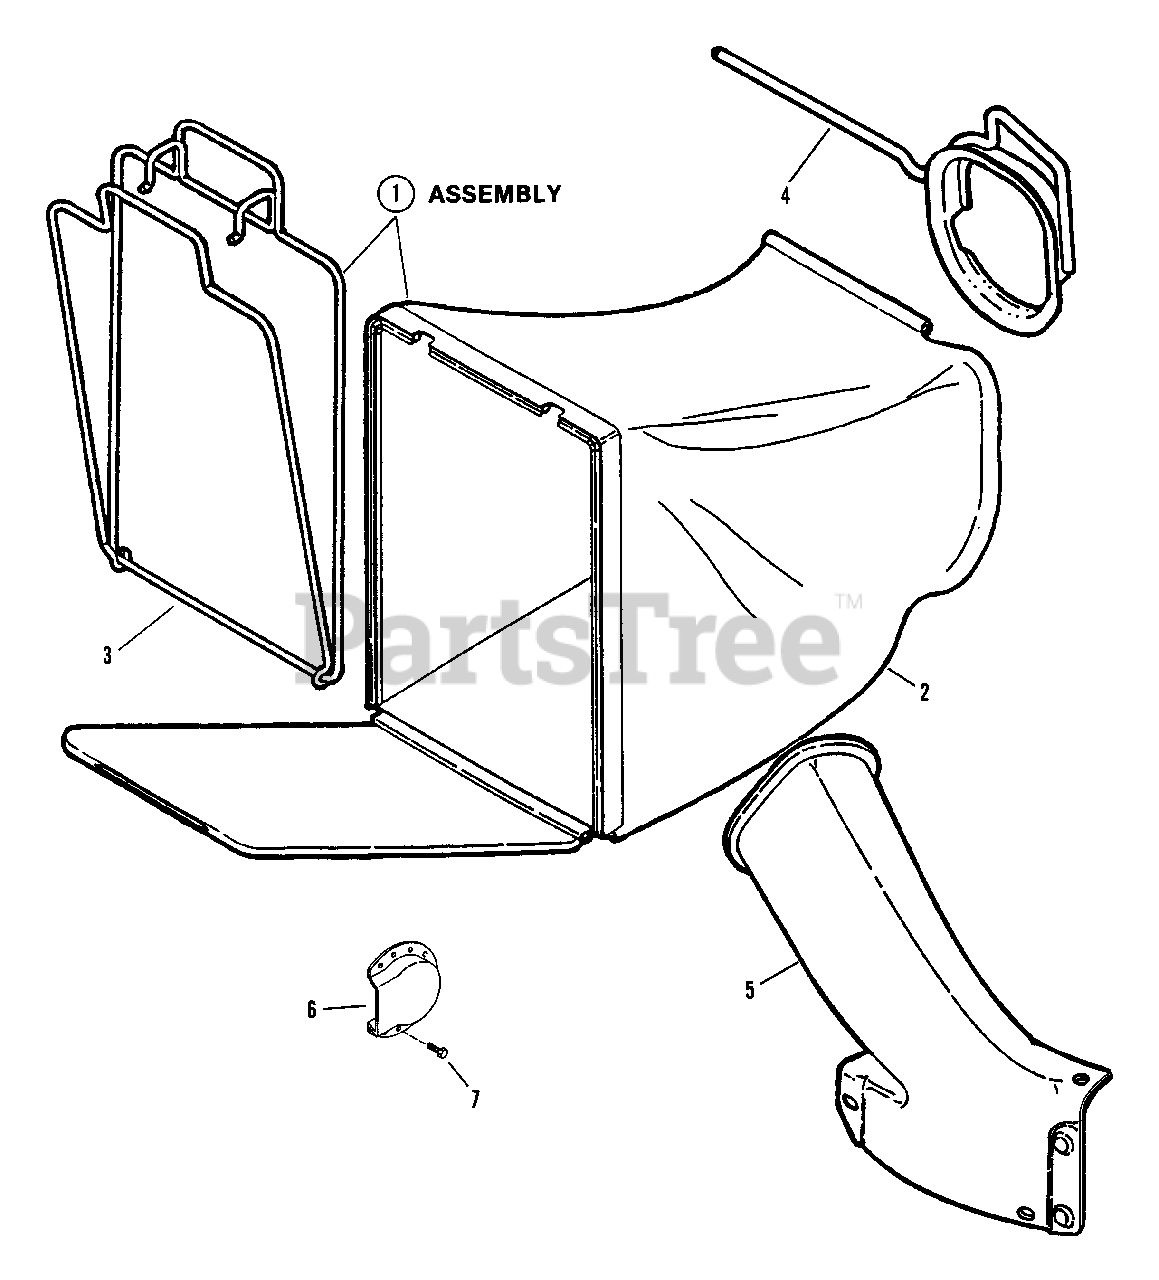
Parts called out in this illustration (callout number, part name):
1	ASSEMBLY, Grass Bag
2	BAG, KWIK-N-EZY
3	ASSEMBLY, Bag Wire
4	CONNECTOR, Grass Bag
5	ADAPTER, Bag
6	DEFLECTOR, Muffler (Briggs)
7	SCREW, #8-18 x 3/8" Hex Head Cap
